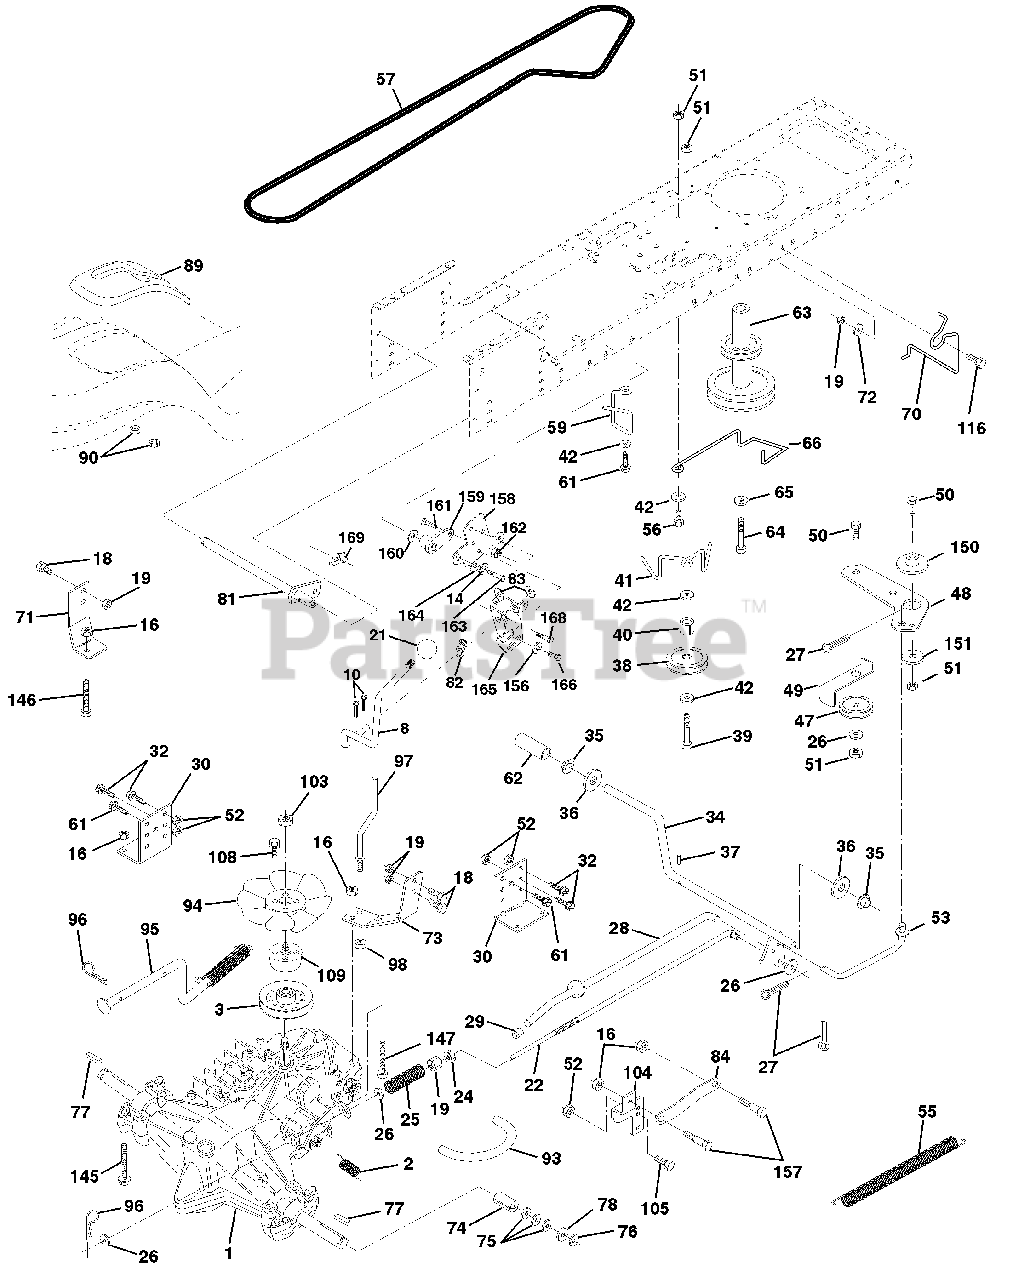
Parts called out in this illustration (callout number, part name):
2	Spring, Return, Brake
3	Pulley, Transaxle
8	Rod Shift Fender Adjust
10	Pin Cotter 1/8 x 1 CAD
14	Washer Lock Hvy Helical
16	Nut Lock Hex W/Ins. 5/16-18 Unc P
18	Bolt Fin Hex 3/8-16 Unc x 1 Gr. 5
19	Nut Lock Hex W/Wsh 3/8-16 Unc
21	Knob, Duckhead 1/2-13
22	Rod, Brake Hydro
24	Nut
25	Spring, Brake Rod
26	Washer
27	Pin Cotter 1/8 x 3/4 CAD.
28	Rod, Parking Brake
29	Cap, Parking Brake
30	Bracket, Transaxle
32	Bolt Hex Hd 5/16-18 Unc x 3/4
34	Shaft, Foot Pedal
35	Bearing, Nylon
37	Pin, Roll
38	Pulley, Idler, Flat
40	Spacer, Split
41	Keeper, Belt Idler
42	Washer 13/32 x 13/16 x 12 Gauge
47	Pulley, Idler, V-Groove
48	Bellcrank Clutch Grnd Prv STL
49	Retainer, Belt
50	Bolt
52	Nut Crownlock 5/16-18
53	Link, Clutch
55	Spring, Return, Clutch
56	Bolt Fin Hex 3/8-16 UNC x 1-1/4
57	V-Belt, Ground Drive
59	Keeper, Center Span
61	Screw Thdrol. 3/8-16 x 3/4 Ty. TT
62	Cover, Pedal
63	Pulley, Engine
64	Bolt Hex 7/16-20 x 4 Gr 5
65	Washer
66	Keeper Belt Engine Hydro
70	Guide Belt Mower Drive RH
71	Strap Torque Lh Hydro
72	Washer 13/32 x 1-1/4 x 12 Ga.
73	Strap Torque Rh Hydro
74	Spacer, Split
75	Washer 25/32 x 1-1/4 x 16 Gauge
77	Key, Square
78	Washer 25/32 x 1-5/8 x 16 Gauge
81	Shaft Asm Cross Tapered
82	Spring Torsion
83	Washer 17/32 x 3/4 x 16 Ga.
84	Link Transaxle
89	Console, Shift
90	Nut, Self-Thd Wsh-hd 1/4 Zinc
93	Line Fuel Hydro 4"
94	Fan, Hydro 7"
95	Control Asm Bypass Hydro
96	Retainer Spring 1" Zinc/Cad
97	Keeper Belt Rh Hydro
98	Nut Keps Hex 3/8-16 Unc
103	Nut Nylon Insert 1/2-20 Unf.
104	Arm, Control Hydro
105	Screw Cap Hex 5/16 x 18 x 1
108	Screw Hex Wh Hd #10-24 x
109	Adaptor Fan Hydro LT Hyd Alum
116	Bolt Rdhd Sq. Neck 3/8-16 x 1.25
145	Bolt Hex Flghd 5/16-18 x Gr. 5
146	Bolt Hex Flghd 5/16-18 x 2-1/4
147	Bolt Hex Flghd 5/16-18 x 1-1/2
150	Bushing Bellcrank Grd Drive
151	Washer 13/32 x 2 x 10 Ga.
156	Washer Srrted 5/16 ID X 1 X .125
157	Bolt Shoulder 5/16-18 Unc -2A
158	Bracket Shift Mount
159	Hub Tapered Flange Shift LT
160	Washer 29/32 x 1-1/4 x 16 Ga.
161	Bolt Rdhd Sqnk 1/4-20 x 3/4 Gr. 5
162	Nut Crownlock 1/4-20 Unc
163	Bolt Hex Fin 1/4-20 Unc x 1 Gr. 5
164	Washer 5/8 x .281 x 10 Ga.
165	Bracket Pivot Lever
166	Screw 5/16-18 x 5/8
168	Bolt Shoulder 5/16-18 x .561
169	Plate Fastening
